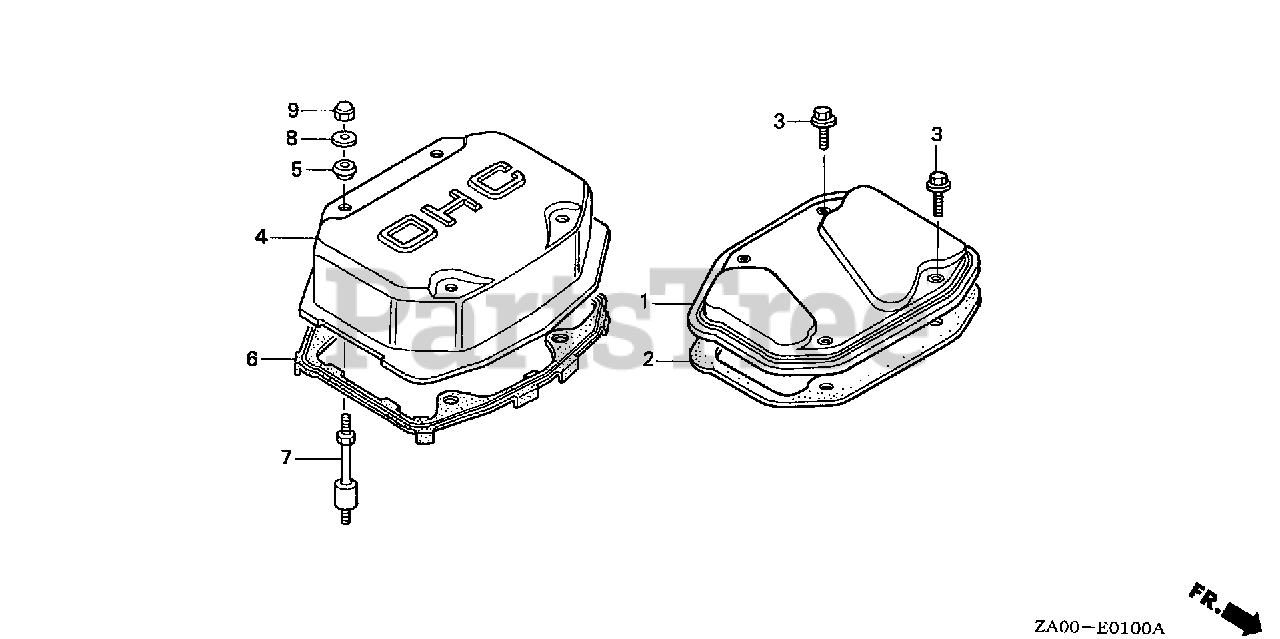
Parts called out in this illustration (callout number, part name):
1	COVER, CYLINDER HEAD
2	GASKET, CYLINDER HEAD COVER
3	BOLT, FLANGE (6X20)
